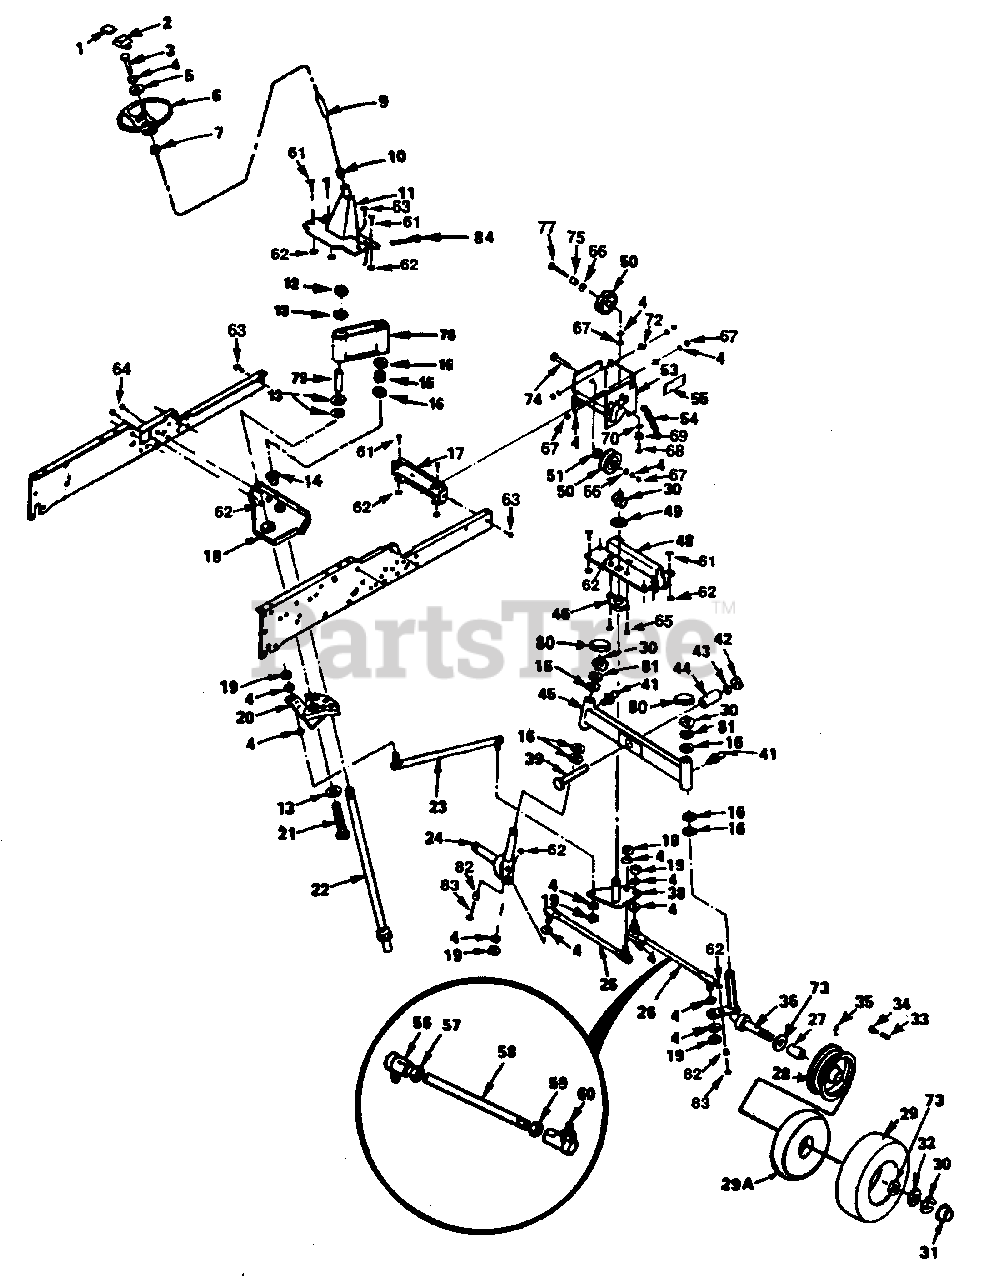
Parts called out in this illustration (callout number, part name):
1	Steering Wheel Decal (AYP part number)
2	Steering Wheel Insert (AYP part number)
3	Hex Bolt (AYP part number)
4	Lock Washer 3/8 (AYP part number)
5	Washer 13/32 x 2-3/8 x 8 Ga. (AYP part number)
6	Steering Wheel (AYP part number)
7	Steering Adapter (AYP part number)
9	Steering Sleeve (AYP part number)
10	Bearing (AYP part number)
11	Steering Support Assembly (AYP part number)
12	Locknut (AYP part number)
13	Washer (AYP part number)
14	Flanged Bearing (AYP part number)
15	Klip Ring (AYP part number)
16	Thrust Bearing (AYP part number)
17	Frame Front Bracket (AYP part number)
18	Steering Support Bracket (AYP part number)
19	Hex Nut 3/8-24 (AYP part number)
20	Sector Assembly (AYP part number)
21	Hex Bolt (AYP part number)
22	Steering Shaft (AYP part number)
23	Drag Link (AYP part number)
24	L.H. Spindle (AYP part number)
26	Tie Rod (AYP part number)
28	8" Front Rim Assembly (AYP part number)
29	Tire (AYP part number)
29A	Tube (not furnished with tractor) (AYP part number)
30	Klip Ring (AYP part number)
31	Front Hub Cap (AYP part number)
32	Washer (AYP part number)
33	Valve Cap (AYP part number)
34	Valve Stem (AYP part number)
35	Grease Fitting (AYP part number)
36	R.H. Spindle (AYP part number)
38	Bellcrank Assembly (AYP part number)
39	Hex Bolt (AYP part number)
41	Grease Fitting (AYP part number)
42	Hex Nut 5/8-11 (AYP part number)
43	Lock Washer 5/8 (AYP part number)
44	Axle Pivot Tube (AYP part number)
45	Front Axle Assembly (AYP part number)
46	Bellcrank Bushing (AYP part number)
48	Axle Bracket (AYP part number)
49	Washer (AYP part number)
50	Idler Pulley (AYP part number)
51	Washer (AYP part number)
53	Idler Bracket Assembly (AYP part number)
54	Extension Spring (AYP part number)
55	Instruction Decal (AYP part number)
56	L.H. Thd. Tie Rod Joint
57	L.H. Hex Jam Nut (AYP part number)
58	Tie Rod (AYP part number)
59	Hex Jam Nut (AYP part number)
60	R.H. Thd. Tie Rod Joint (AYP part number)
61	Hex Bolt (AYP part number)
62	Lock Nut
63	Thd. Rolling Washer Hex Screw (AYP part number)
64	Hex Bolt (AYP part number)
65	Hex Bolt 3/8-16 x 1 (AYP part number)
66	Washer (AYP part number)
67	Hex Nut 3/8-16 (AYP part number)
68	Hex Bolt (AYP part number)
69	Clutch Handle Bushing (AYP part number)
70	Washer (AYP part number)
71	Nut
72	Idler Bracket Mounting Pin (AYP part number)
73	Washer (AYP part number)
74	Hex Bolt (AYP part number)
75	Split Spacer (AYP part number)
76	Collar Weld Assembly (AYP part number)
77	Bolt (AYP part number)
79	Tube (AYP part number)
80	Dust Cap Cover (AYP part number)
81	Washer (AYP part number)
82	Spindle Stop (AYP part number)
83	Hex Bolt (AYP part number)
84	Cotter Pin (AYP part number)
